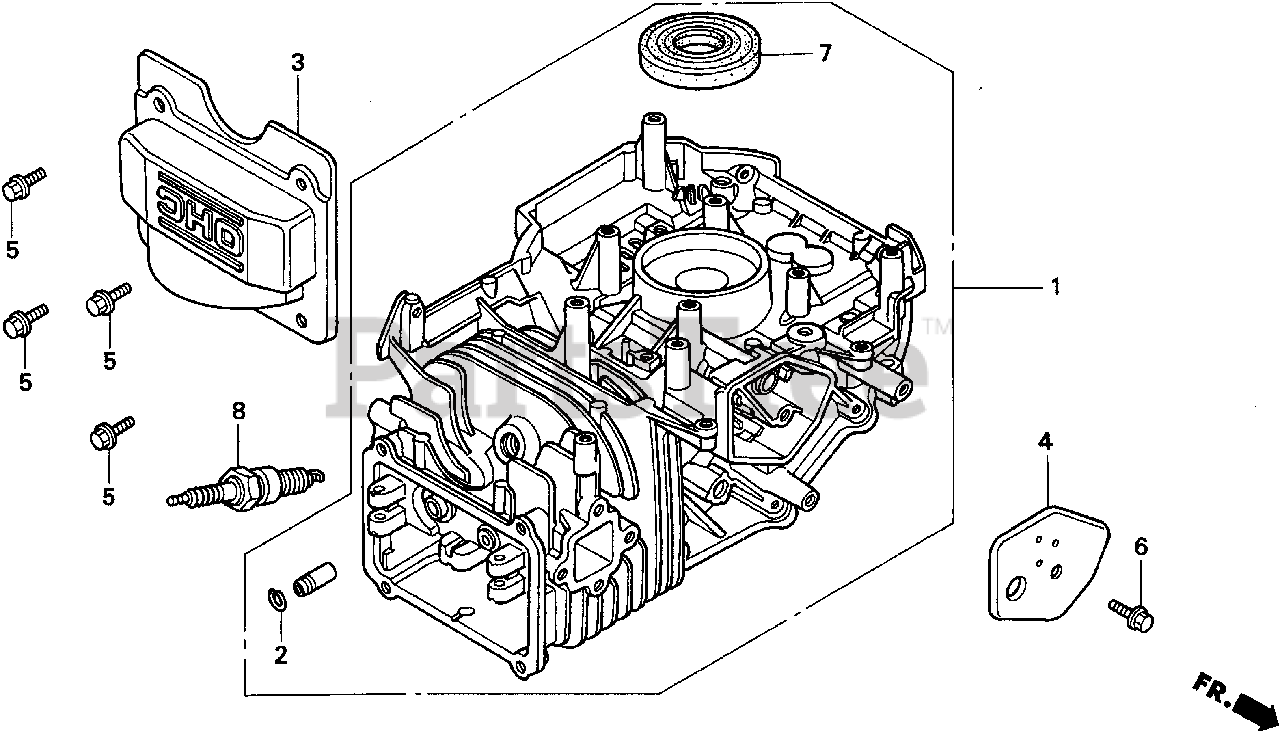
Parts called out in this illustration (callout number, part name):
1	CYLINDER ASSY. (010)
2	CLIP, VALVE GUIDE
3	COVER, HEAD
4	COVER, BREATHER (BREATHER VALVE ASSY.)
5	BOLT, FLANGE (6X12) (CT200)
6	BOLT, FLANGE (6X14)
7	OIL SEAL (25.4X62X6)
8	SPARK PLUG (BPR6ES) (NGK)
